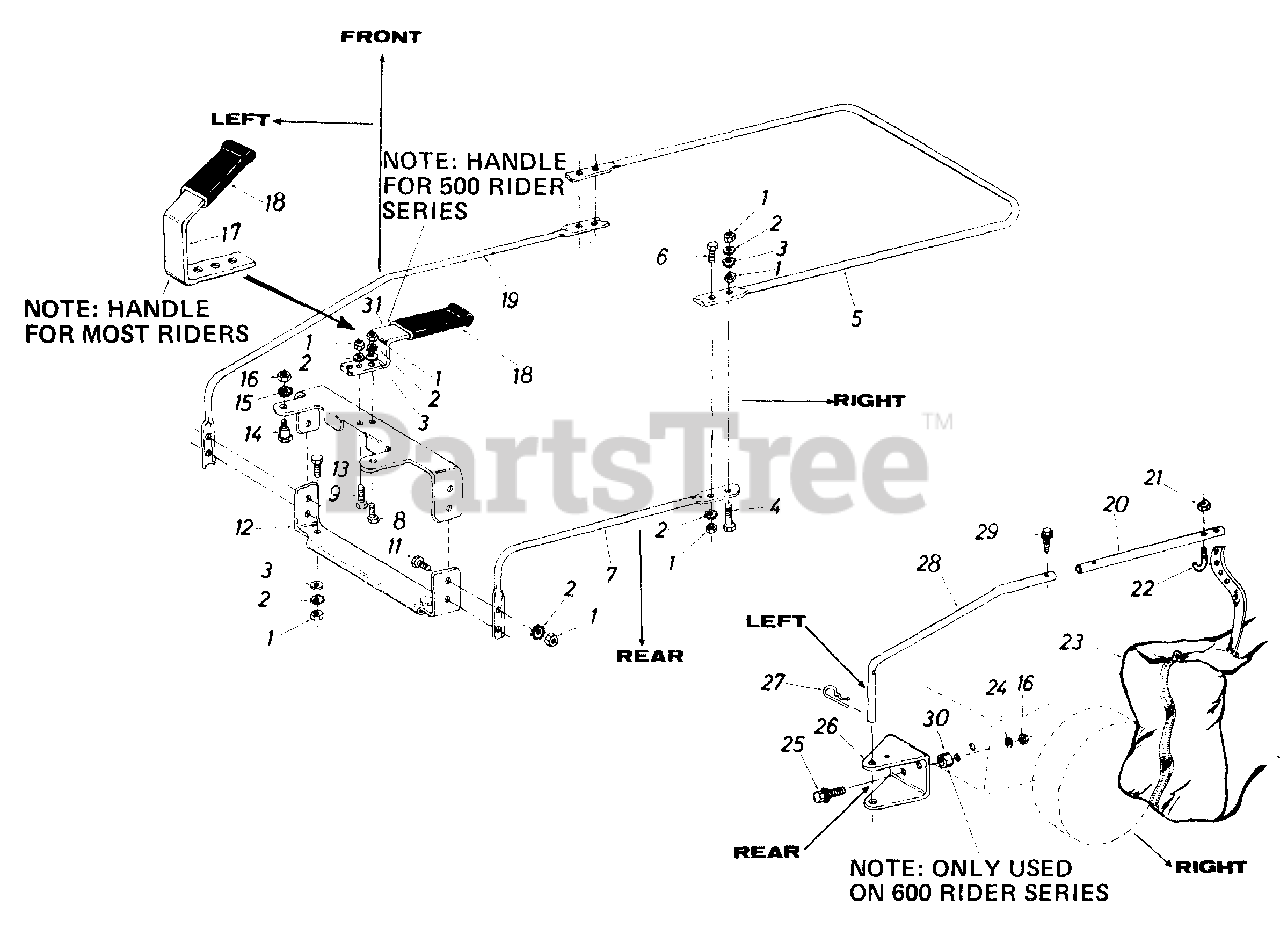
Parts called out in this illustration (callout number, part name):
1	Hex Nut 1/4-20 Thd.
2	Ext. L-Wash. 1/4" Scr.
3	Fl-Wash. .281 I.D. x .50 O.D.
4	Hex Scr. 1/4-20 x 1.50" Lg.
5	Upper Frame Half
6	Hex Scr. 1/4-20 x 1.00" Lg.
7	Lower Frame Tubing
8	Hex Scr. 1/4-20 x .62" Lg.
9	Hex Scr. 1/4-20 x .75" Lg.
11	Hex Scr. 1/4-20 x 1.0" Lg.
12	Lower Opening Support
13	Hex Scr. 1/4-20 x .50" Lg.
14	Shld. Scr. .437 Dia. x .350
15	Ext. L-Wash. 5/16" Scr.
16	Hex Nut 5/16-18 Thd.
18	Grip-Black
19	Lower Frame Arm
23	Grass Catcher Bag
24	L-Wash. 5/16" Scr.
25	Hex Sems Scr. 5/16-18 x .75" Lg.
26	Hitch Bracket
27	Internal Cotter Pin 5/8" Dia.
28	Lower Holding Arm
29	Hex Wash. Hd. Self-Tap .50" Lg.
31	Handle
